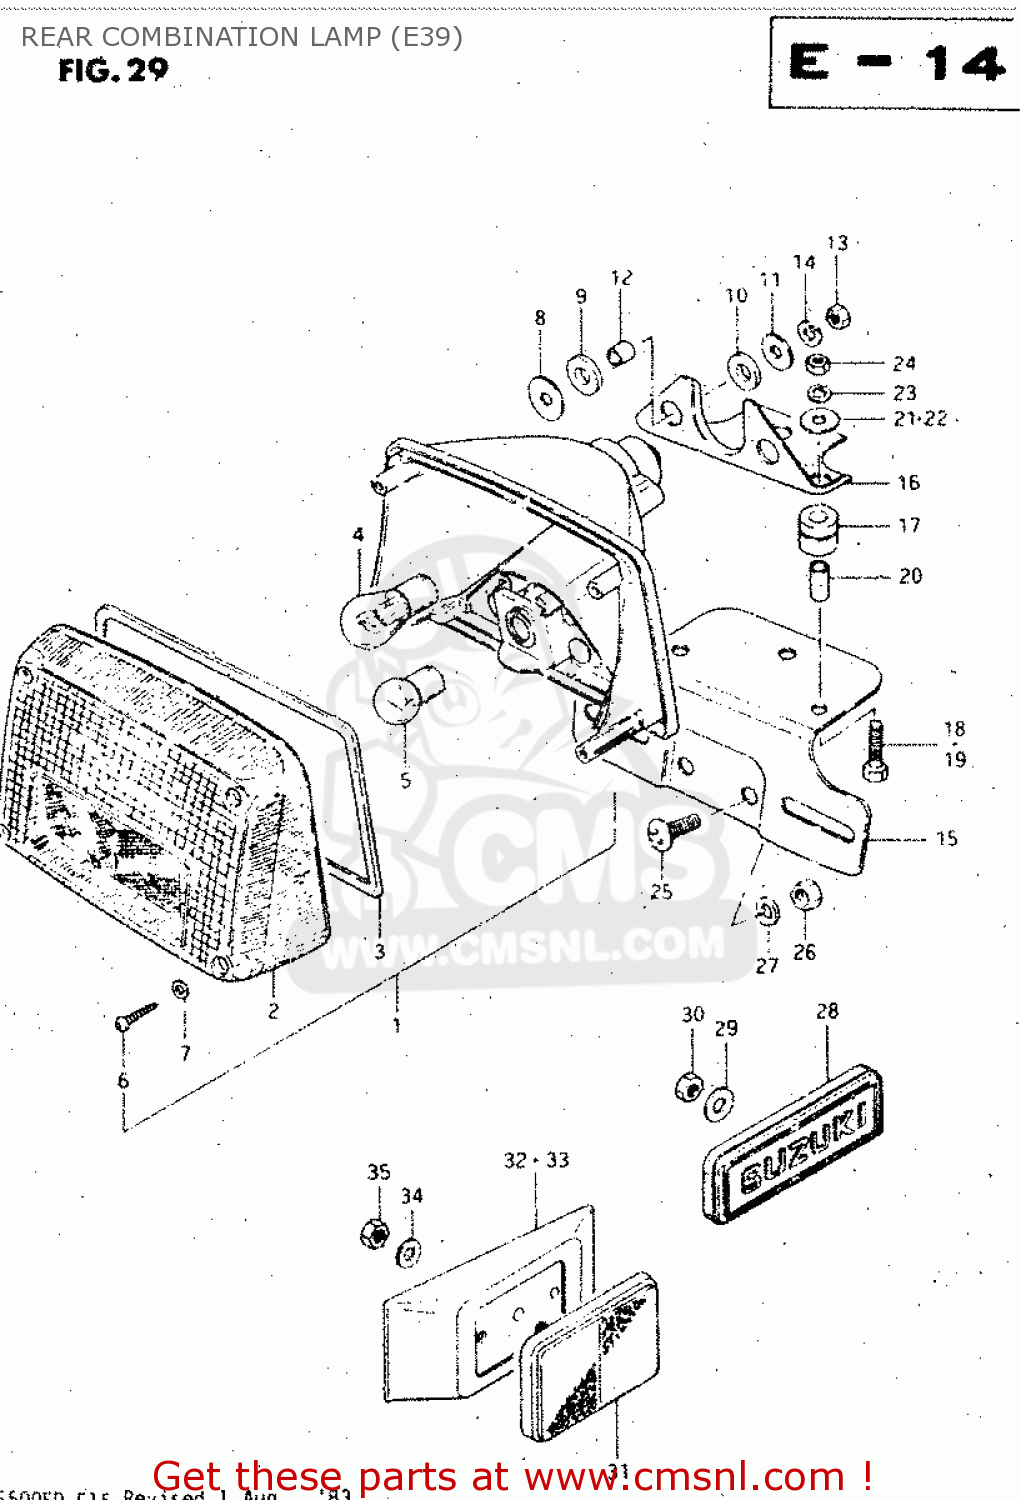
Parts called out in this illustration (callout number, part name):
1	LAMP ASSY, REAR COMBINATION
2	LENS,RR COMBI
3	GASKET (NAS)
4	BULB,12V,12W
5	BULB
6	SCREW,REAR COMBINATION LAMP
7	GASKET (NAS)
8	WASHER
9	CUSHION
10	CUSHION
11	WASHER(6,5X22X1.6)
12	SPACER(6.1X9X7.5)
13	NUT
14	LOCK WASHER
15	BRACKET, LICENCE PLATE
16	BRACKET,LICENSE PLATE
17	CUSHION, BRACKET
18	BOLT
19	BOLT
20	SPACER (6.4X9X15.5)
21	WASHER
22	WASHER
23	LOCK WASHER
24	NUT
25	SCREW
26	NUT
27	LOCK WASHER
28	EMBLEM, REAR SIDE
29	WASHER
30	NUT
31	REFLECTOR,REFLEX
32	SPACER, RH
33	SPACER, LH
34	WASHER
35	NUT
